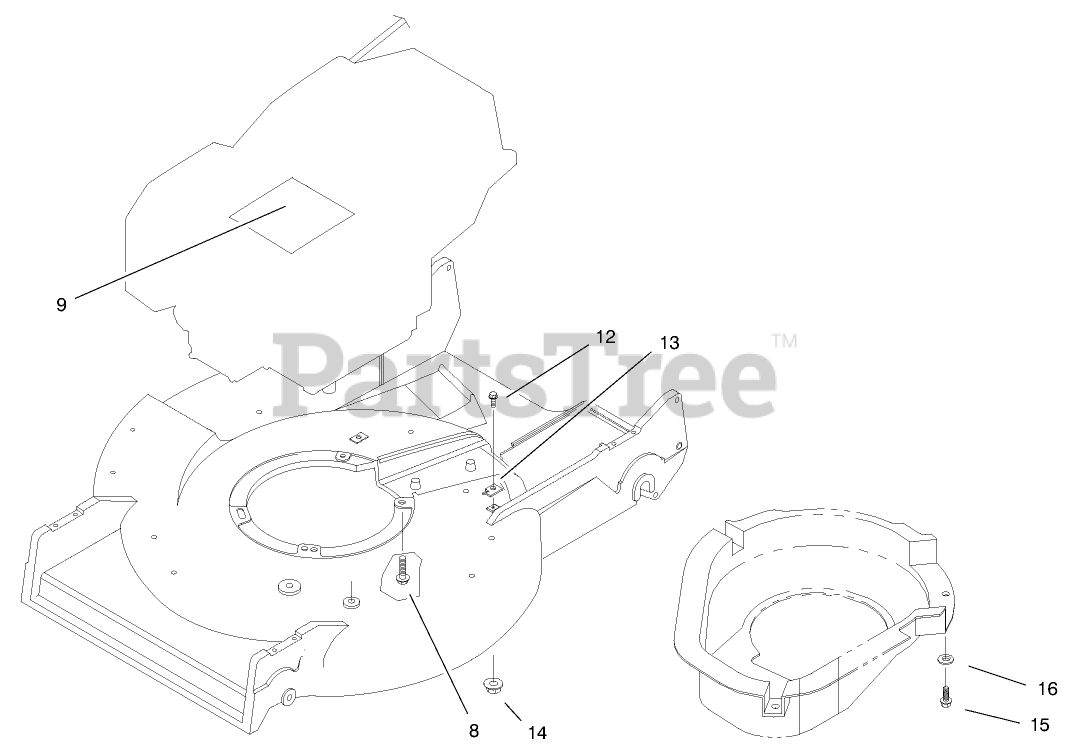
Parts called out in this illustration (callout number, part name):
8	SCREW-MOUNT, ENGINE
9	DECAL-ENGINE
12	SCREW-HH
13	CLAMP-CABLE
14	NUT-LOCK, NI
15	SCREW-HWHTF
16	WASHER-PLAIN
